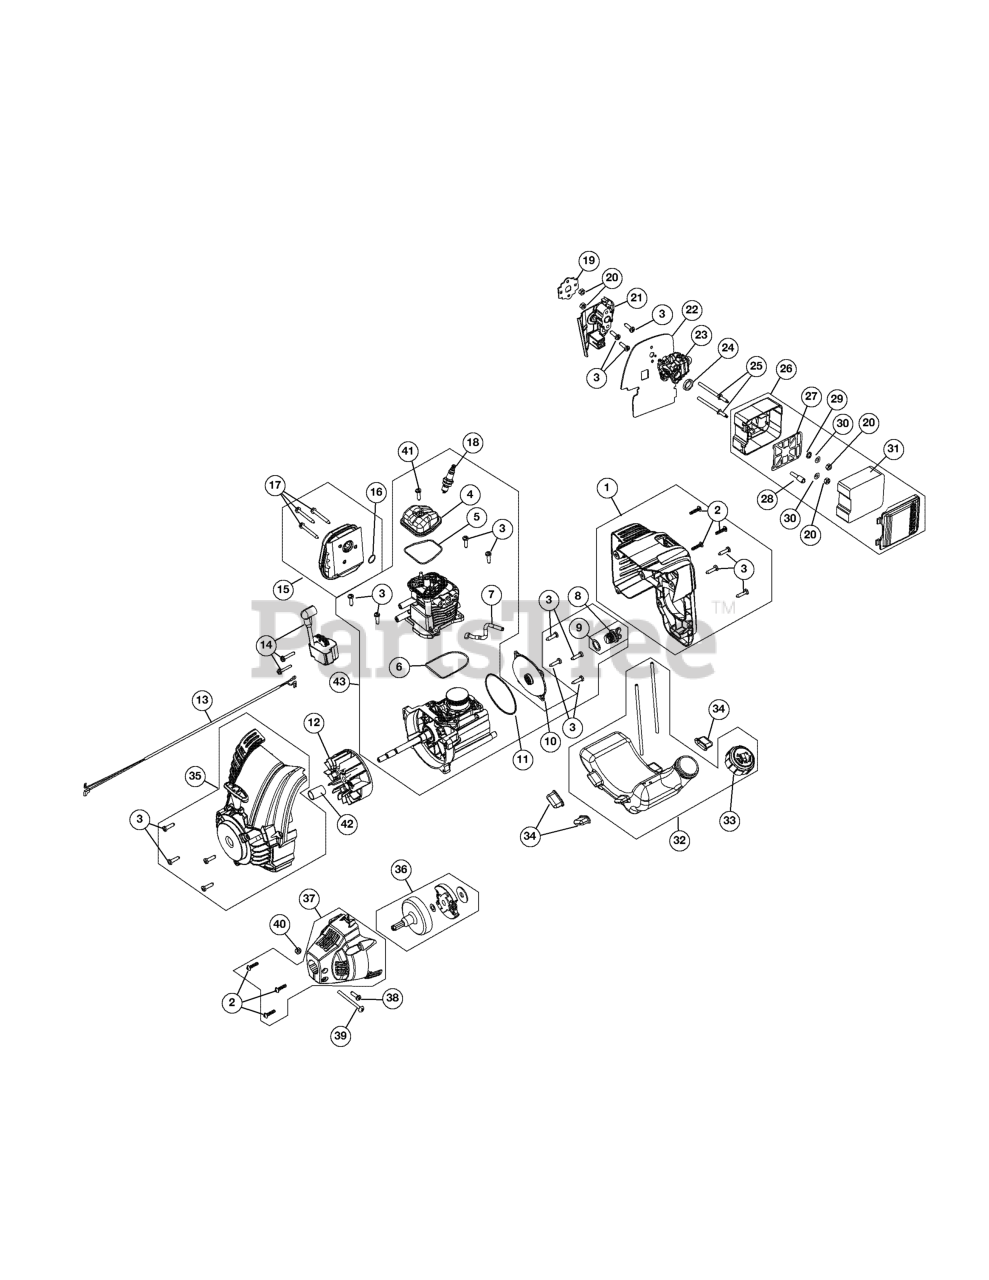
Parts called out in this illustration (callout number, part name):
1	Engine Cover Assembly (Incl Ref No. 2 & 3)
2	Cover Screw
3	Starter Screw
4	Rocker Cover
5	Rocker Cover O-Ring
6	Cylinder O-Ring
7	Breather Hose
8	Oil Plug (Incl Ref No. 9)
9	Oil Plug O-Ring
10	Crankcase Cover
11	Crankcase Cover O-ring
12	Flywheel Assembly
13	Lead Wires
14	Module Assembly
15	Muffler Assembly (Incl Ref No. 16 & 17)
16	Muffler Gasket
17	Muffler Screw
18	Spark Plug
19	Insulator Gasket
21	Insulator
22	Carburetor Gasket
23	Carburetor w/Primer
24	Carburetor O-Ring
25	Air Filter Mounting Screw
26	Air Cleaner Cover Assembly (Incl Ref No. 27-31)
27	Air Filter Plate
28	Breather Tube Assembly
29	Air Cleaner O-Ring
31	Air Filter
32	Fuel Tank Assembly w/Fuel Lines (Incl Ref No. 34)
33	Fuel Cap
34	Fuel Tank Pads
35	Starter Housing Assembly (Incl Ref No. 3)
36	Clutch Assembly
37	Clutch Cover (Incl Ref No. 2)
38	Anti-Rotation Screw
39	Clamp Screw
41	Rocker Cover Screw
42	Spacer
43	Shortblock Assembly
